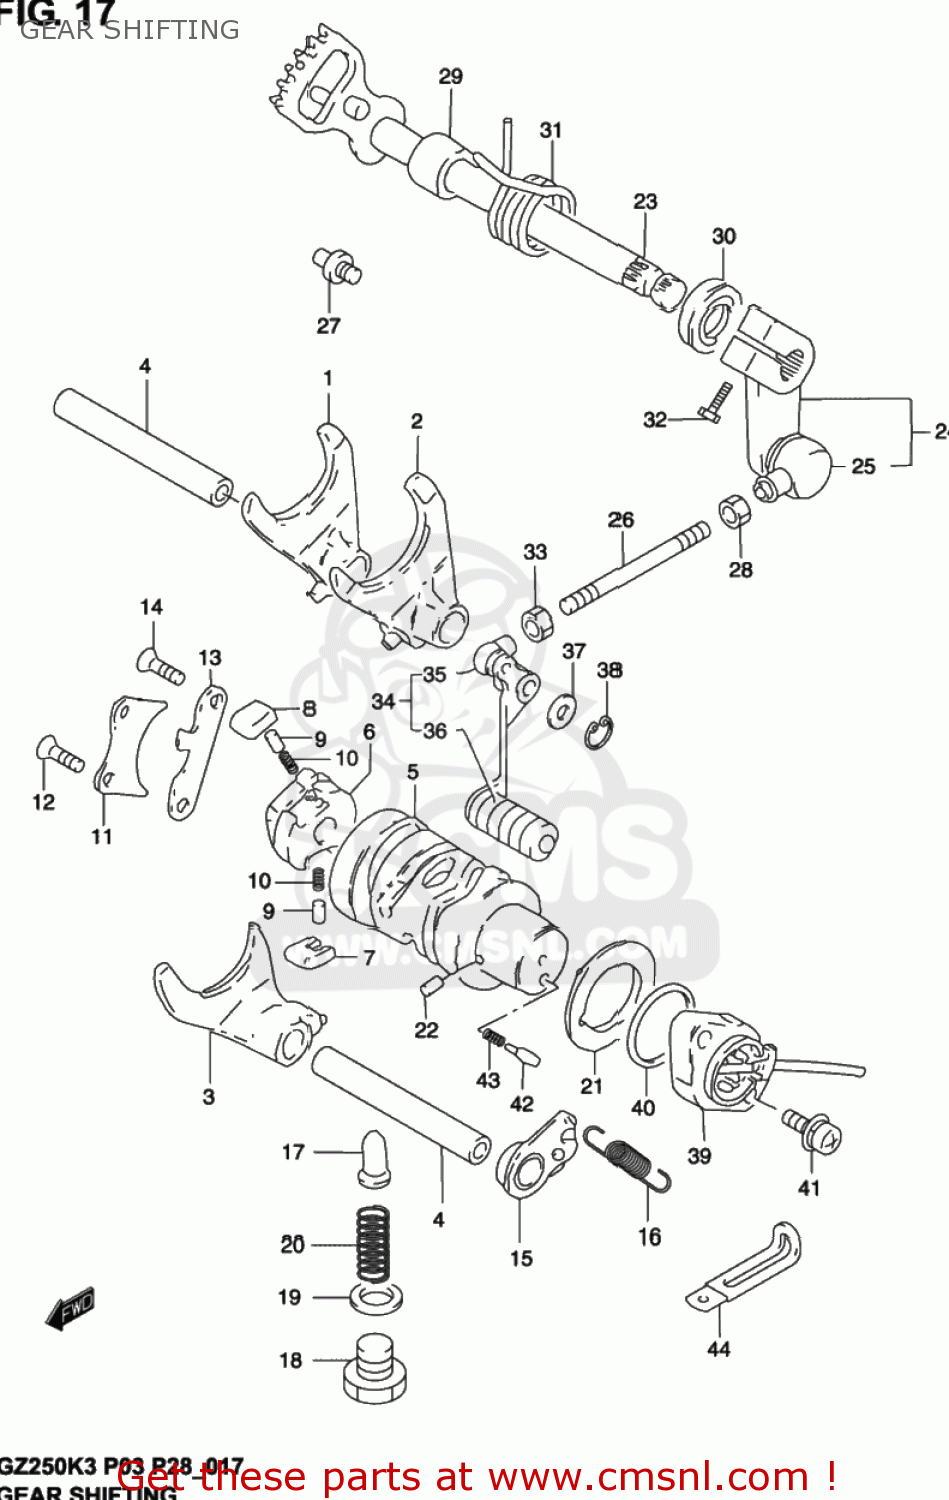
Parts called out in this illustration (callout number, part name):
1	FORK,GEAR SHIFT NO.1
2	FORK,GEAR SHIFT NO.2
3	FORK,GEAR SHIFT NO.3
4	SHAFT,GEAR SHIFT FORK
5	CAM,GEAR SHIFT
6	GEAR,GEAR SHIFT CAM DRIVEN
7	PAWL,GEAR SHIFT NO.1
8	PAWL,GEAR SHIFT NO.2
9	PIN(5X8)
10	SPRING
11	LIFTER,GEAR SHIFT POLE
12	SCREW
13	GUIDE,GEAR SHIFT CAM
14	SCREW
15	STOPPER,GEAR SHIFT CAM
16	SPRING
17	STOPPER,GEAR SHIFT CAM NO.2
18	PLUG (14X12)
19	GASKET(13.8X18.8X4.8) (NAS)
20	SPRING
21	PLATE,GEAR SHIFT CAM STOPPER
22	PIN
23	SHAFT,GEAR SHIFT
24	ARM,GEAR SHIFT LINK
25	COVER,DUST
26	ROD,GEAR SHIFT LINK
27	STOPPER,GEAR SHIFT ARM
28	NUT
29	SPACER(12X20X15.3)
30	OIL SEAL
31	SPRING
32	BOLT
33	NUT
34	LEVER ASSY,GEAR SHIFT
35	COVER,DUST
36	RUBBER,GEAR SHIFT PEDAL
37	WASHER(12.5X20X1)
38	CIRCLIP,12 MM
39	BASE ASSY,NEUTRAL SW TERMINAL
40	O RING(D:2.4,ID:26.2)
41	SCREW
42	PIN(5X15.5)
43	SPRING
44	CLAMP(L:45)
